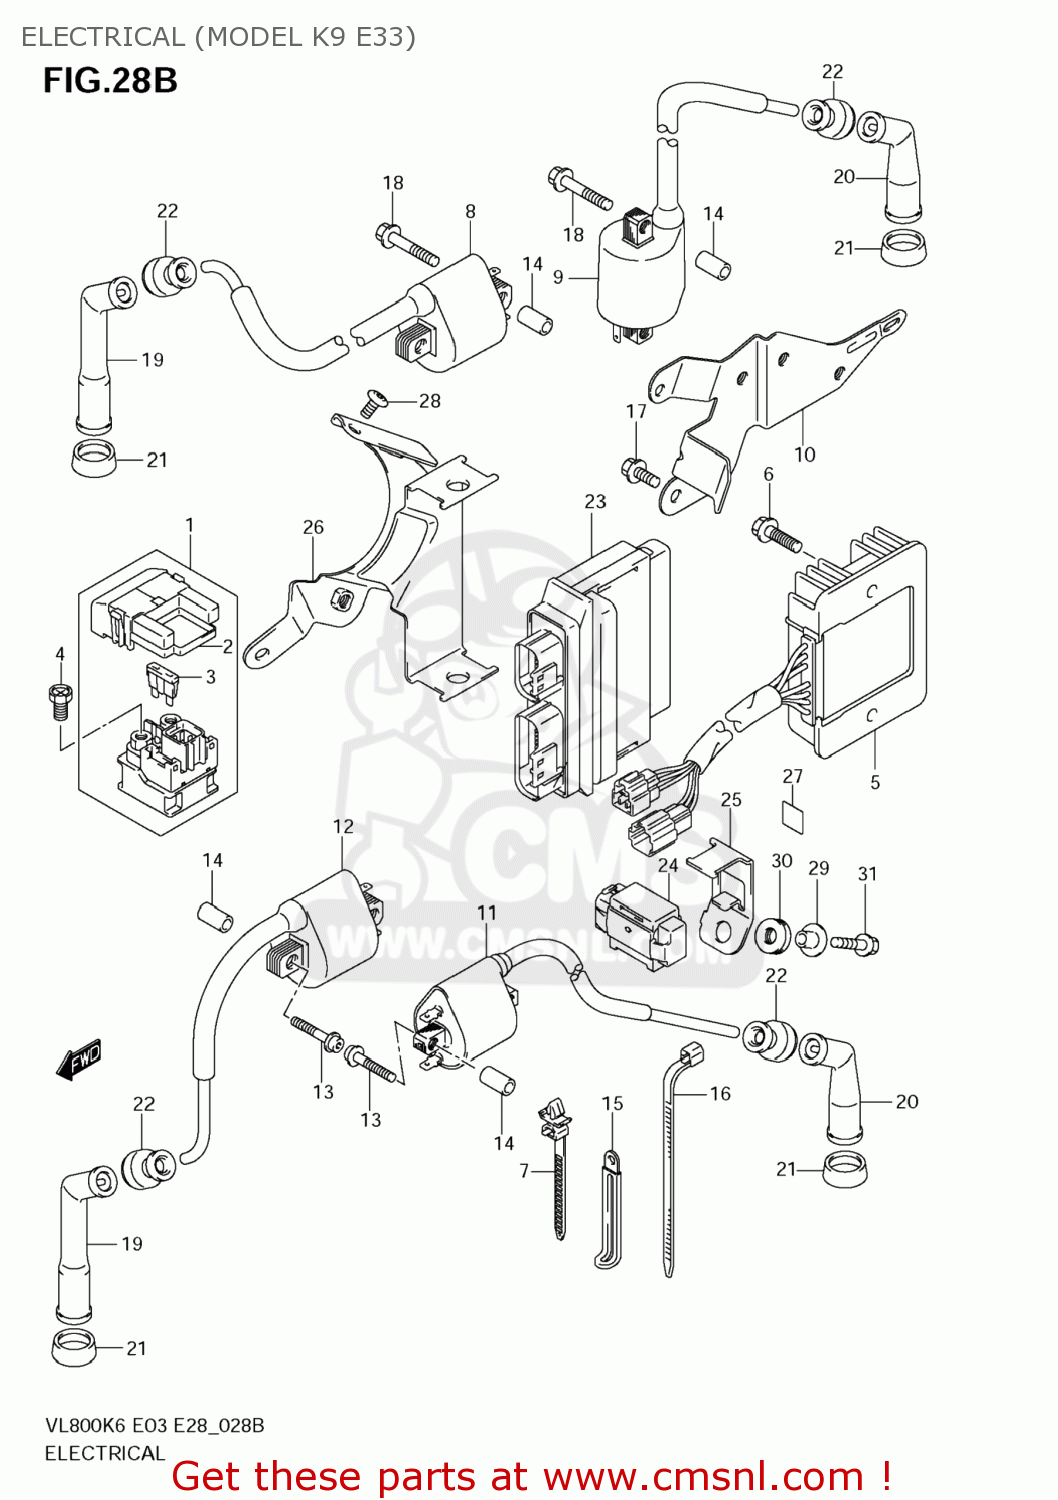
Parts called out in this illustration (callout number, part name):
1	RELAY ASSY,STARTING MOTOR
2	COVER
3	FUSE(30A)
4	SCREW(6X8)
5	RECTIFIER ASSY
6	SCREW
7	CLAMP(L:90)
8	COIL ASSY,IGNITION RR
9	COIL ASSY,IGNITION RR
10	BRACKET,IGNITION COIL RR
11	COIL ASSY,IGNITION FR
12	COIL ASSY,IGNITION
13	BOLT(5X35)
14	SPACER(6.4X10X18)
15	CLAMP(L:80)
16	CLAMP(L:190)
17	BOLT
18	BOLT
19	CAP,SPARK PLUG
20	CAP,SPARK PLUG
21	SEAL,SPARK PLUG
22	SEAL,HIGH TENSION CORD
23	CONTROL UNIT,FI
24	SENSOR ASSY,FUEL CUT
25	BRACKET,FUEL CUT SENSOR
26	BRACKET,FI CONTROL UNIT
27	CUSHION,CABLE GUIDE
28	SCREW(6X12)
29	SPACER(6.2X8.4X6.9)
30	CUSHION
31	BOLT
